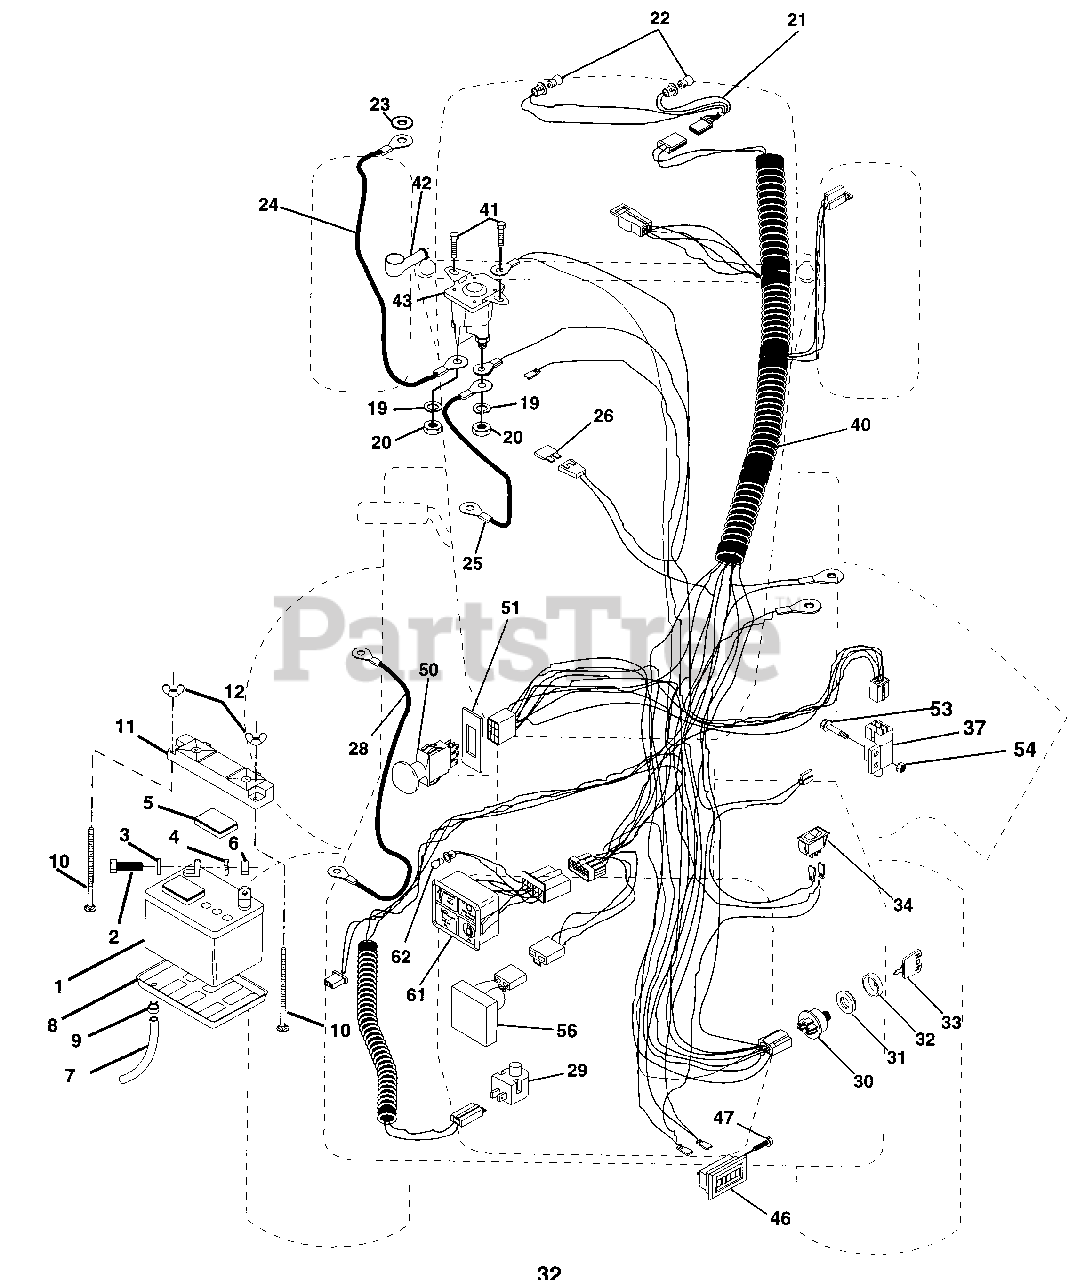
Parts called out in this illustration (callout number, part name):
1	Battery
2	Bolt Hex Head 1/4-20 x 3/4
3	Washer, Lock 1/4
4	Washer 9/32 x 5/8 x 16 Ga
5	Caps, Battery
6	Nut Fin Hex 1/4-20
7	Tube, Plastic
8	Tray, Battery
9	Clamp, Hose
10	Bolt, Carriage 1/4-20 x 7-1/2
11	Guard, Terminal
12	Nut, Wing 1/4-20
19	Washer, Lock 1/4
20	Nut, Jam Hex 1/4-20
21	Harness, Socket, Light
22	Bulb, Light
23	Washer, Lock Int. Tooth 1/4
24	Cable, Starter
25	Cable, Battery
28	Cable, Ground
29	Switch, Plunger
30	Switch, Ign
31	Nut, Ignition Switch
32	Cover, Switch Key
34	Switch, Light
37	Intlk Switch
40	Harness, Ign.
41	Screw 1/4-20 x 1/2
42	Cover, Terminal Red
43	Solenoid
46	Meter, Hour
47	Screw #10-24 x 1/2
50	Switch, PTO
51	Ring, Retainer, PTO
53	Screw, Hex Washer Hd #10-32 x 1
54	Nut, Keps #10-32
56	Sensor, Lo-Volt
61	Light Pkg Asm
62	Bulb, Light Pkg.
